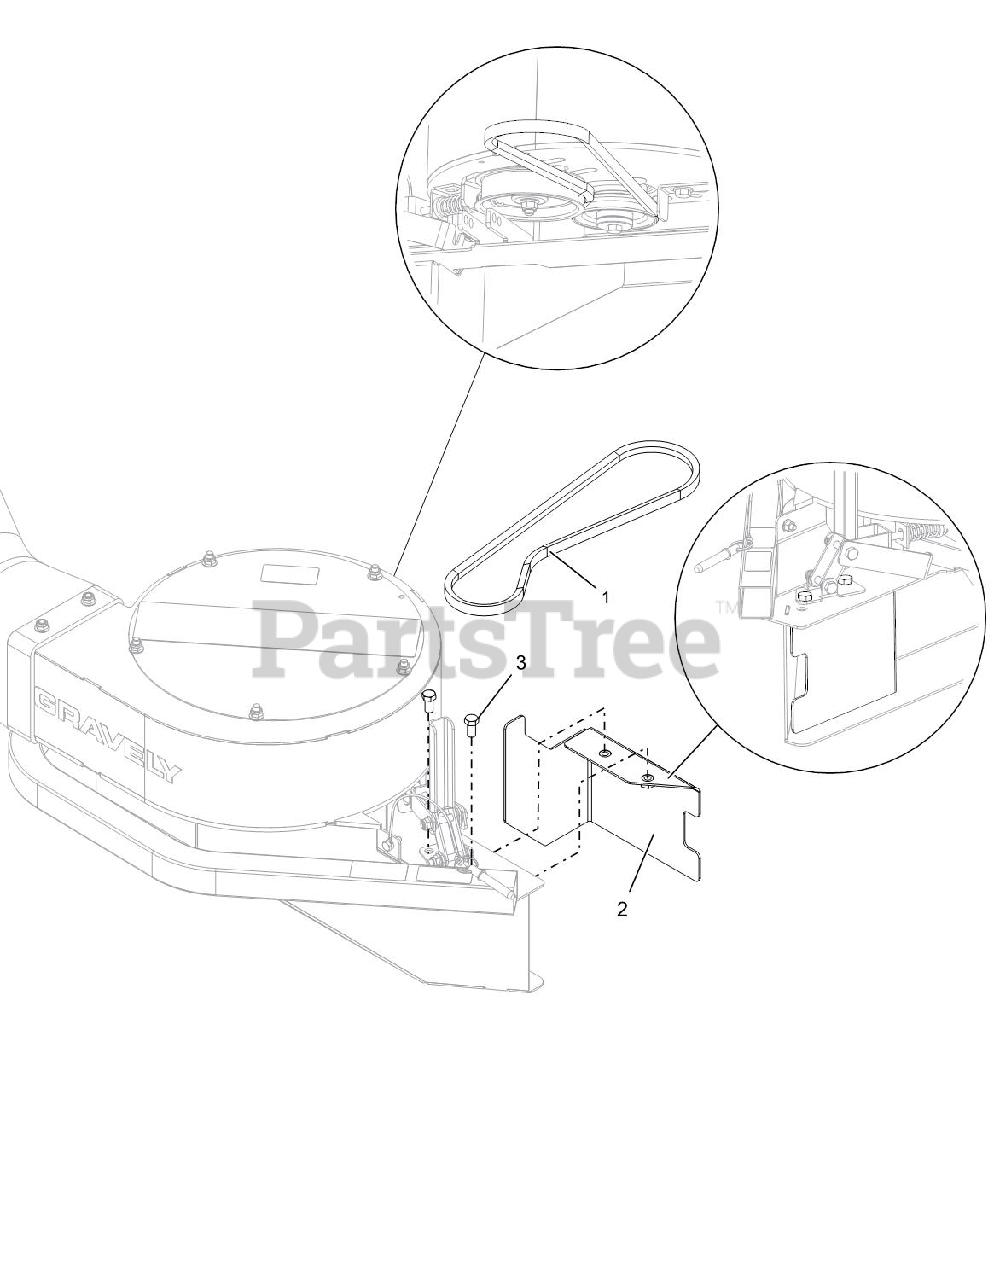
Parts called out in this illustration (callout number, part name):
1	V-BELT, 4L WRAPPED CLUTCHING
2	48" FRT BLOWER BAFFLE WMT -BLK
3	@BLT-HEX .38-16X.75 GR5 YWZC
